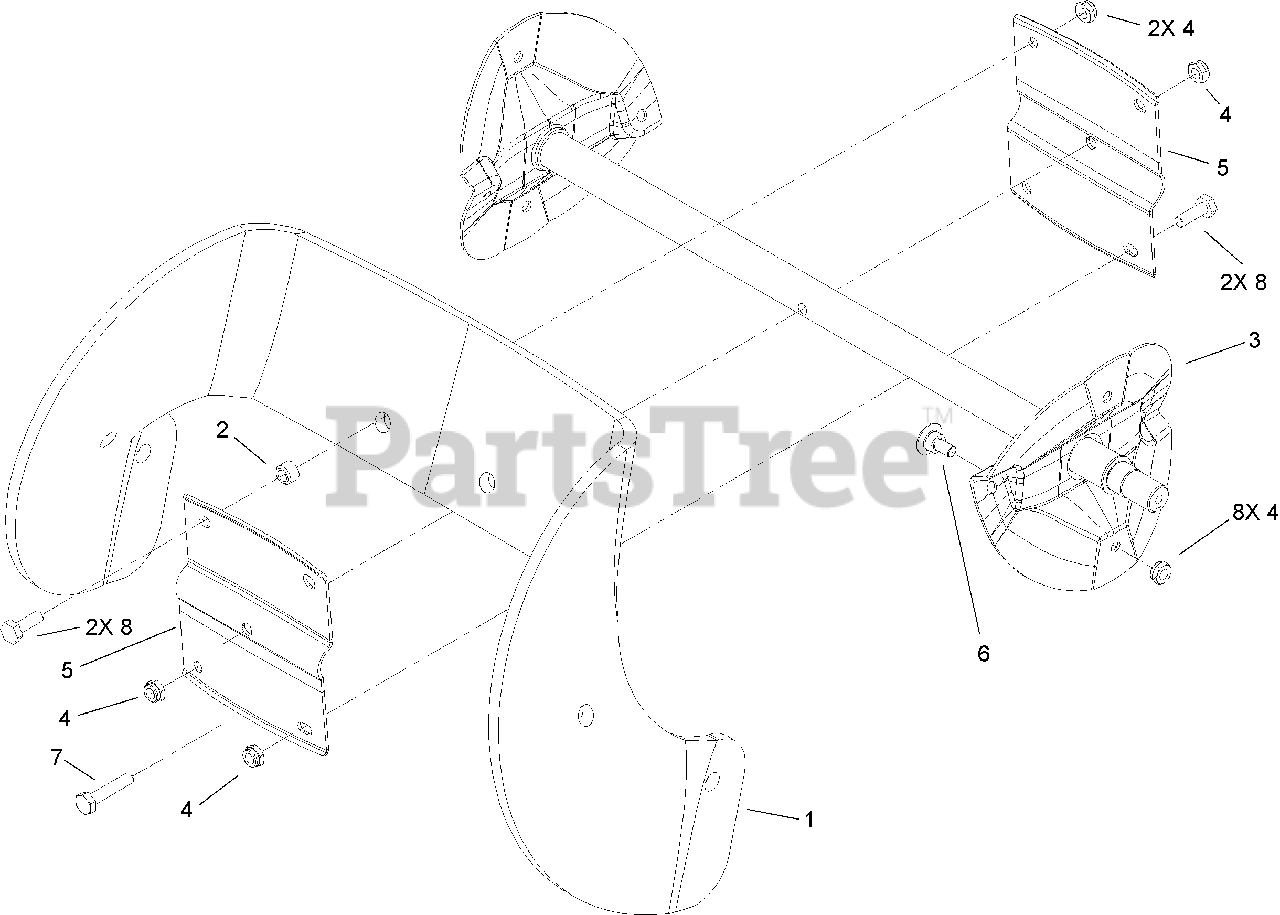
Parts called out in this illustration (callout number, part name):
1	BLADE-ROTOR
2	SPACER-BLADE, ROTOR
3	ROTOR ASM
4	NUT-LOCK, NI
5	HALF-ROTOR
6	SCREW
7	SCREW-HH
8	SCREW-HH
